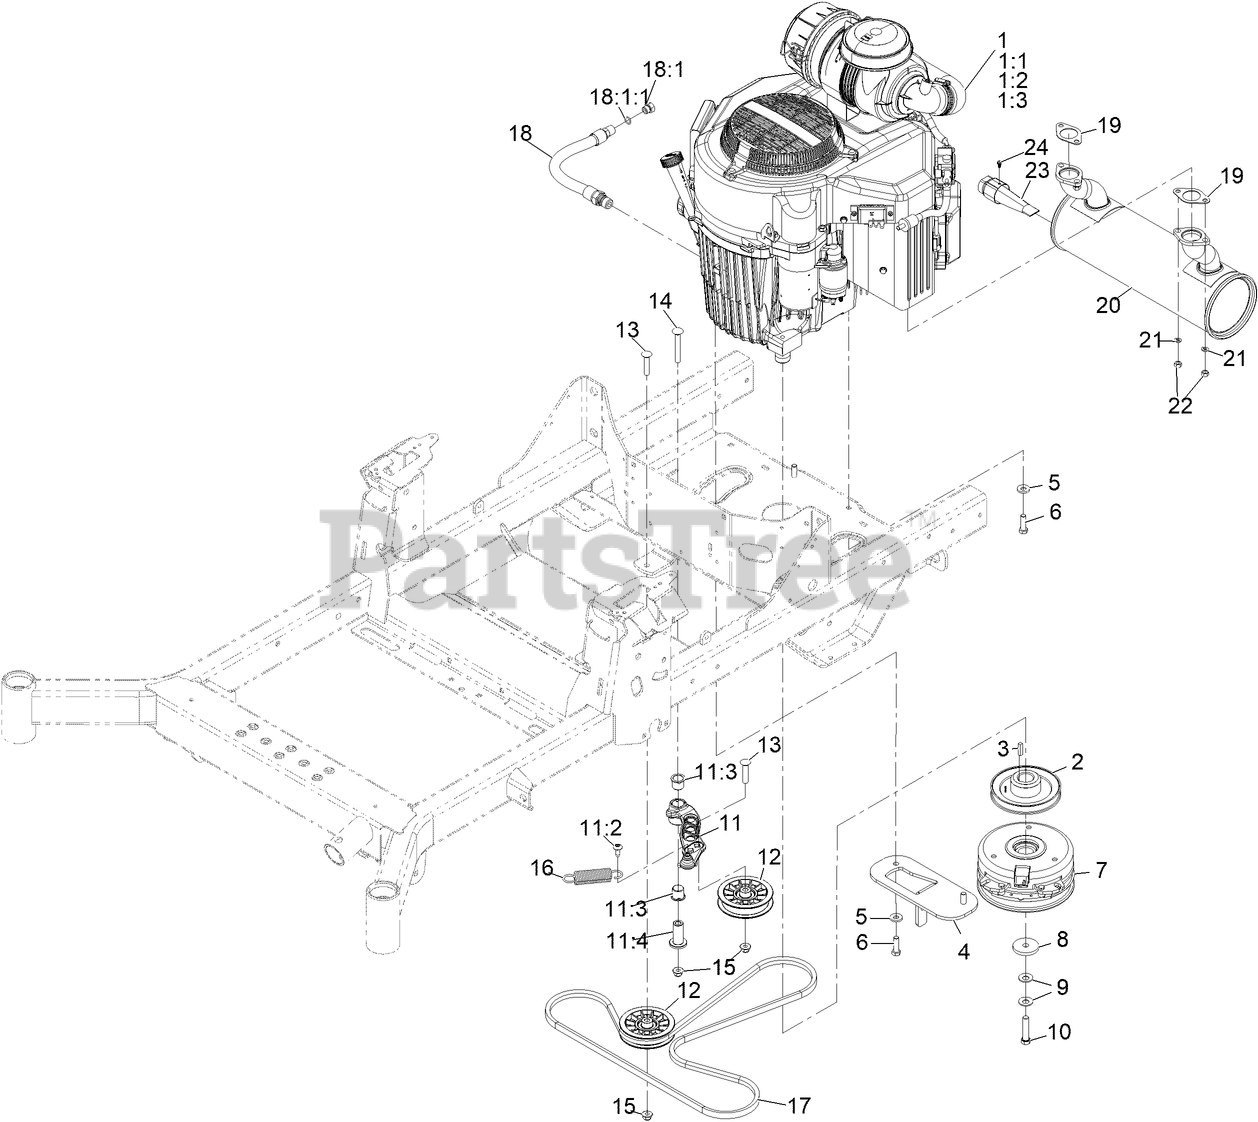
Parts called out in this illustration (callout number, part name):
1:1	Kawasaki 49065-7007 Engine Oil Filter
1:2	Kawasaki 11013-7044 Engine Air Filter
1:3	Kawasaki 11013-7045 Safety Filter
2	SHEAVE, ENGINE
4	Anchor-Clutch
5	WASHER-BELLEVILLE
6	SCREW-HH
7	CLUTCH-225 FTLBS
8	WASHER-CLUTCH
9	WASHER-SPRING
10	SCREW-HH W/LOCTITE
11	ASM, PUMP IDLER
11:2	SCREW, TAPTITE
11:3	BUSHING, IGUS
11:4	Spacer, Idler Pivot
12	PULLEY-FLAT IDLER
13	SCREW-CARR
14	SCREW-CARR
15	NUT-HF, NI
16	SPRING-EXTENSION
17	BELT-V
18	ENGINE OIL DRAIN HOSE ASM
18:1	PLUG-HH
18:1:1	O-RING
19	GASKET, EXHAUST
20	MUFFLER, KAWASAKI
21	WASHER-LOCK
23	Spark Arrestor, 1.5"
24	Screw-Ground
